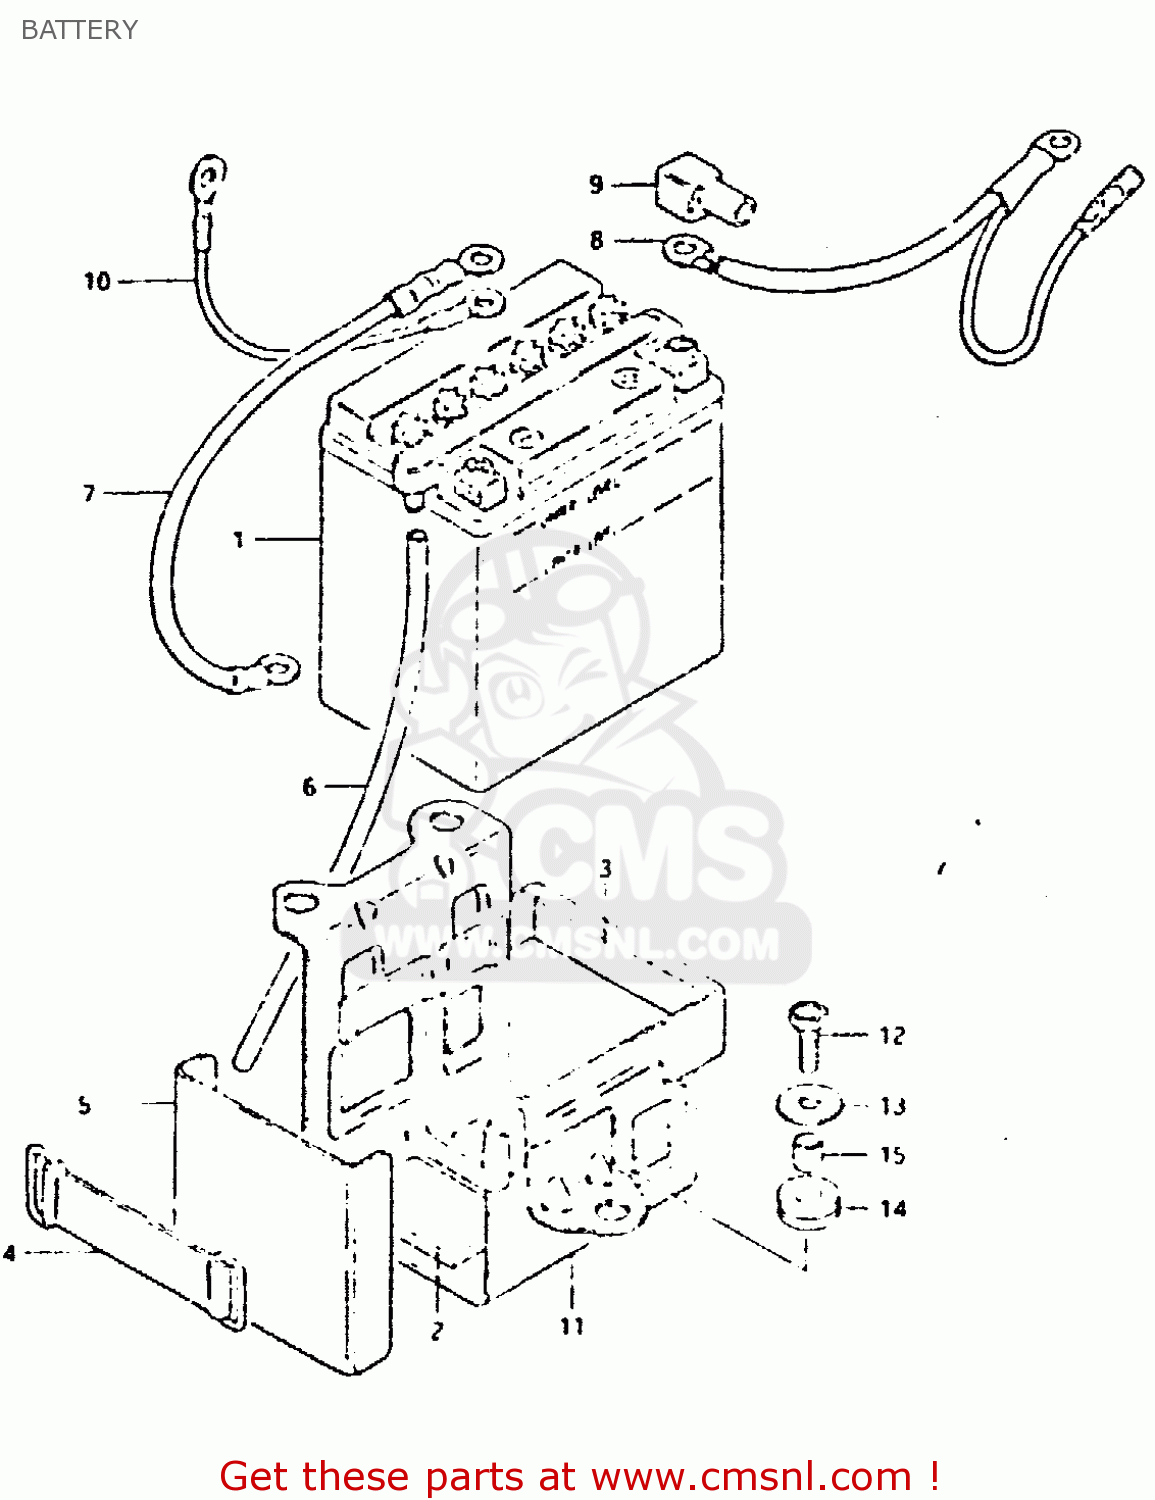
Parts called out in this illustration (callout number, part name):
1	BATTERY ASSY (12V)
2	CUSHION,BATTERY
3	PROTECTOR,20X9
4	BAND
5	COVER,BATTERY
6	HOSE,BATTERY EXHAUST
7	CORD,BATTERY MINUS
8	WIRE,BATTERY PLUS
9	CAP,TERMINAL
10	WIRE
11	HOLDER,BATTERY
12	BOLT
13	WASHER
14	CUSHION
15	SPACER (6.1X9X9)
